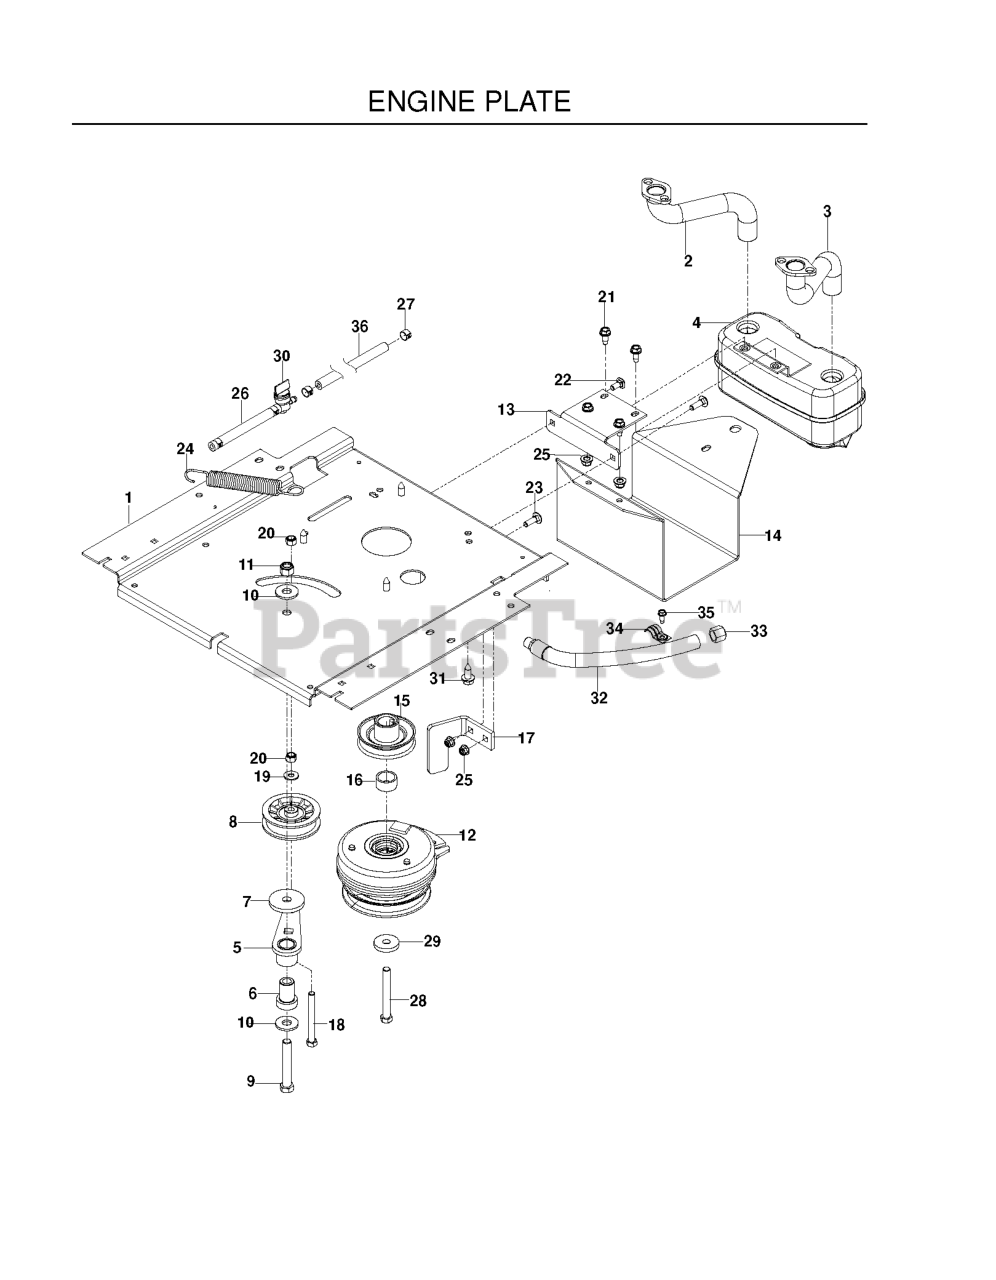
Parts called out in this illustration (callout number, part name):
1	PLATE ENGINE, BLACK
2	RP.EXHAUST.TUBE.LH.BS/TWIN
3	RP.EXHAUST.TUBE.RH.BS/TWIN
4	MUFFLER ASM TWIN
5	IDLER ARM WELDMENT
6	IDLER SPINDLE
7	HEAVY WASHER
8	PULLEY, IDLER
9	HCS 1/2C X 3 1/4
10	WASH USS FLAT 1/2
11	NUT 1/2-13 HEX NYLOC ZD
12	CLUTCH, 105 FT-LBS
13	BRACKET, MUFFLER, BLACK
14	GUARD, MUFFLER, BLACK
15	PULLEY, ENGINE
16	T & B SPACER
17	STOP, CLUTCH, BLACK
18	HCS 3/8-16X3 1/2 GR5
19	WASHER 5/16 FLAT
20	NUT 3/8-16 NYLOC
21	BOLT 5/16-18 X 3/4
22	BOLT 5/16C X 3/4" CARRIAGE
23	RHSNB 5/16C X 1
24	SPRING, DECK DRIVE
25	5/16-18 NYLOC FLANGE NUT
26	HOSE 1/4 X 8
27	HOSE CLAMP
28	HCS 7/16-20X3-1/2 GR 5 ZN
29	CLUTCH, WASHER
30	FUEL VALVE
31	HHFS 3/8-16 X 1.0 THD FORMING
32	OIL DRAIN HOSE
33	DRAIN CAP
35	SCREW 1/4 X 5/8
36	FUEL LINE 24"
